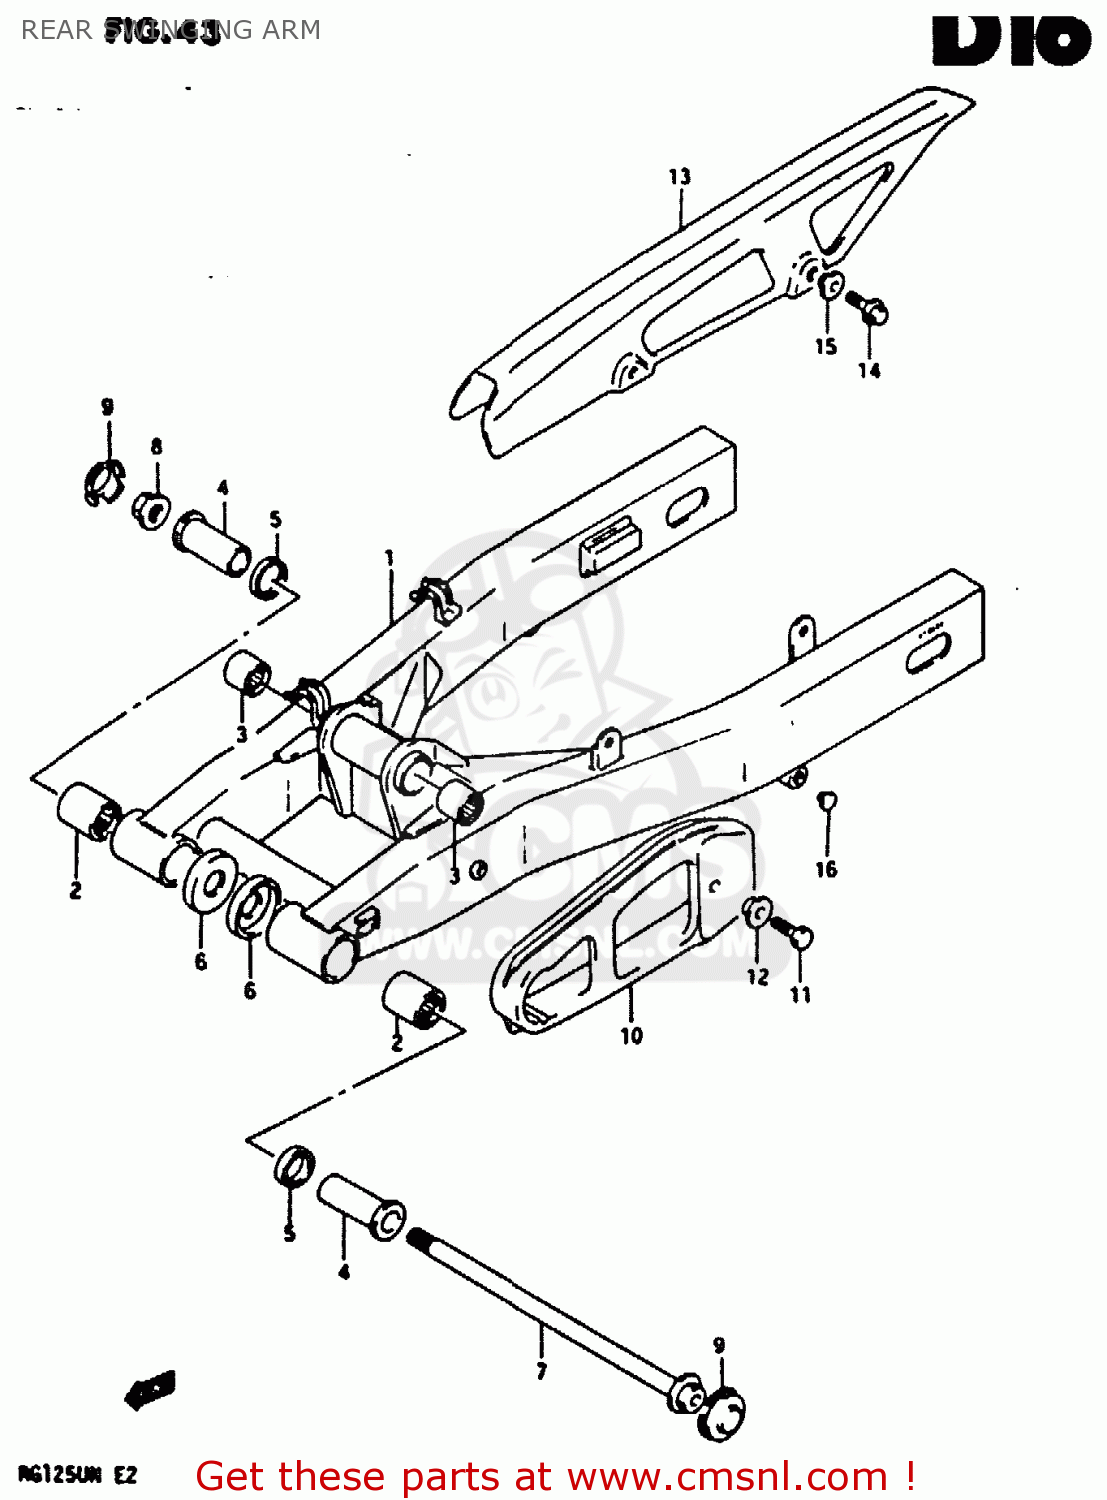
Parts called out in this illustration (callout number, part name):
1	SWINGING ARM ASSY, REAR (SILVER)
2	BEARING(20X27X30)
3	BEARING(17X24X25)
4	SPACER,RR SWGARM PIVOT OUTER
5	OIL SEAL
6	COVER, PIVOT DUST
7	SHAFT, PIVOT
8	NUT
9	CAP,CUSHION LEVER
10	BUFFER,CHAIN TOUCH DEFENSE
11	BOLT
12	WASHER
13	CASE,CHAIN
14	BOLT
15	WASHER
16	CAP(OD:12)
